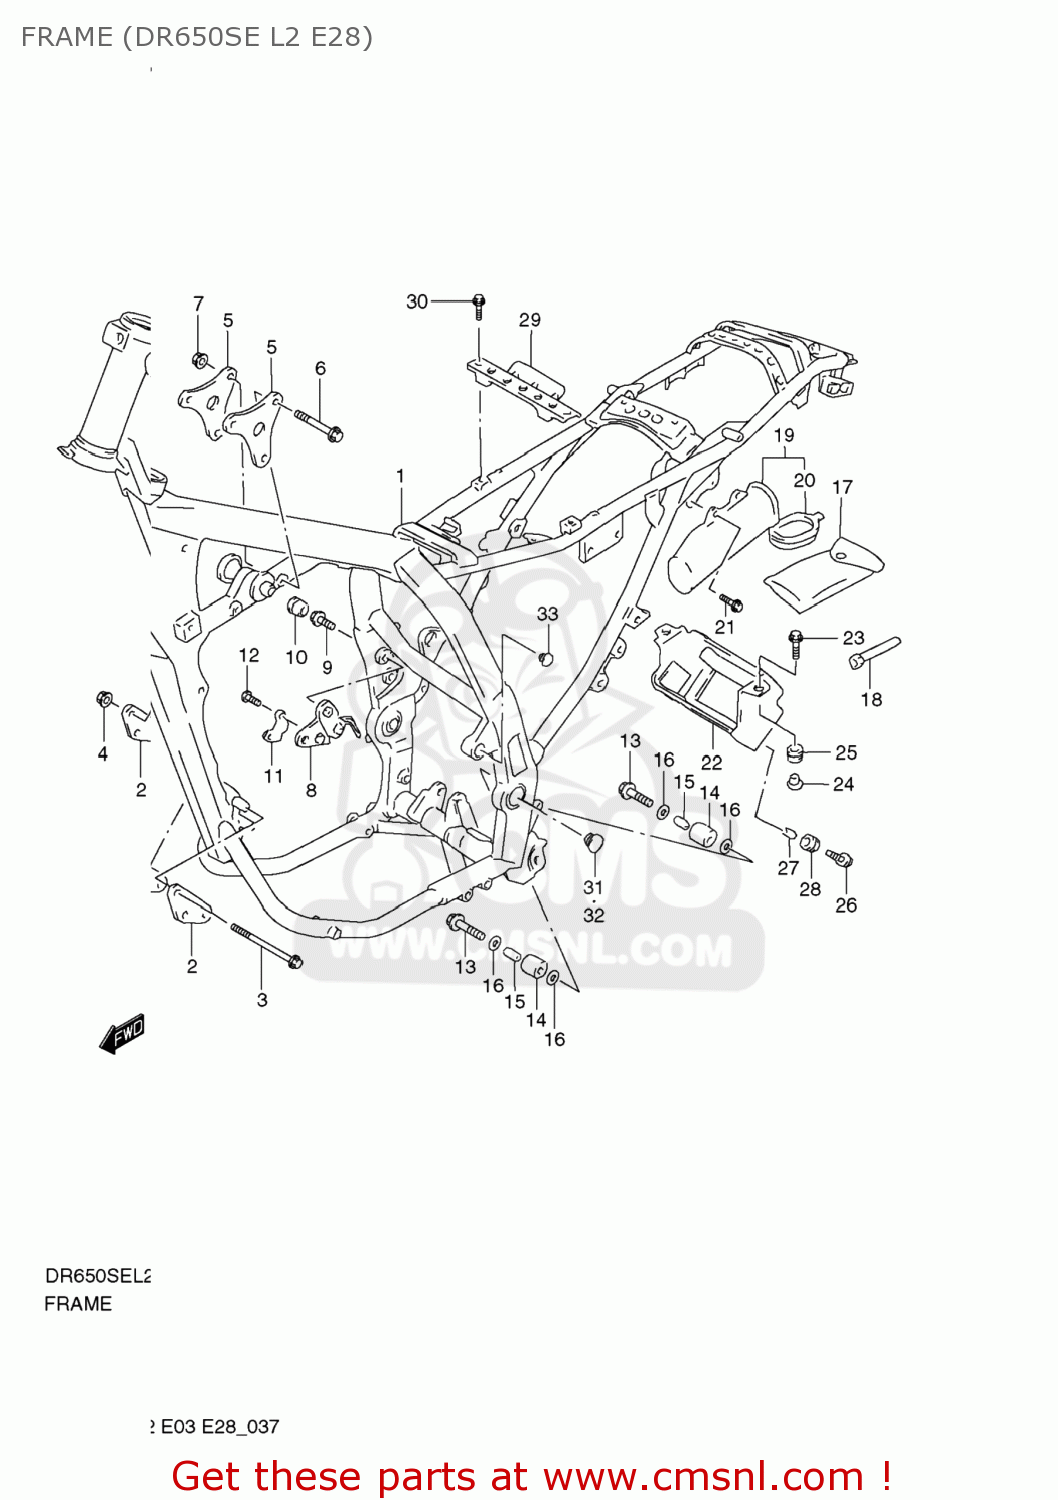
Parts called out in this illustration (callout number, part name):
1	FRAME(GRAY)
2	PLATE,ENG MTG FR
3	BOLT(8X100)
4	NUT
5	PLATE,ENG MTG UPR
6	BOLT(8X55)
7	NUT
8	PLATE,ENG MTG RR,R
9	BOLT
10	PLUG(OD:22)
11	BRACKET,STOP SWITCH
12	SCREW
13	BOLT(8X38)
14	ROLLER,CHAIN CONTROL UPR
15	SPACER(8.6X12X25.5)
16	WASHER
17	TOOL ASSY
18	SPARK PLUG WRENCH(16)
19	HOLDER,TOOL
20	CAP,HOLDER
21	BOLT(6X16)
22	HOLDER,BATTERY
23	BOLT(6X20)
24	WASHER
25	CUSHION
26	BOLT(6X16)
27	SPACER(6.1X9X7.5)
28	CUSHION
29	PLATE,BATTERY FITING
30	BOLT
31	PLUG,FRAME PIVOR,R
32	PLUG,FRAME PIVOR,L
33	PLUG,FRAME BOSS
